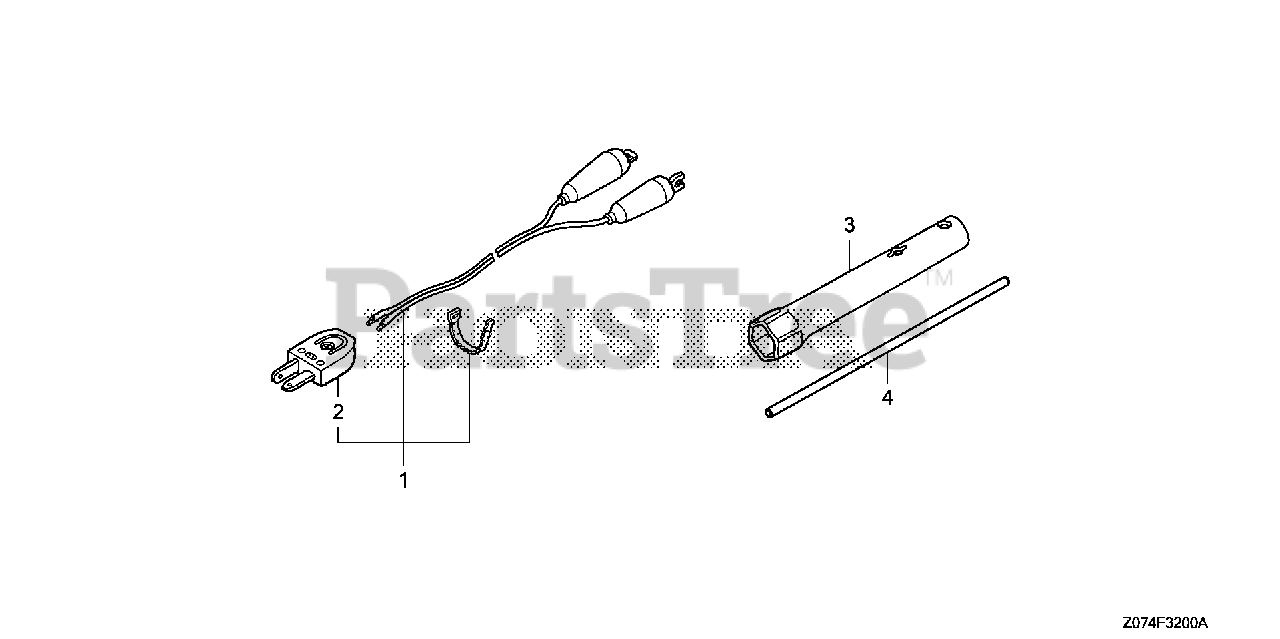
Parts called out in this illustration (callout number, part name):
1	WIRE ASSY., CHARGE
1	WIRE ASSY., CHARGE (2M)
2	PLUG ASSY., RECEPTACLE
